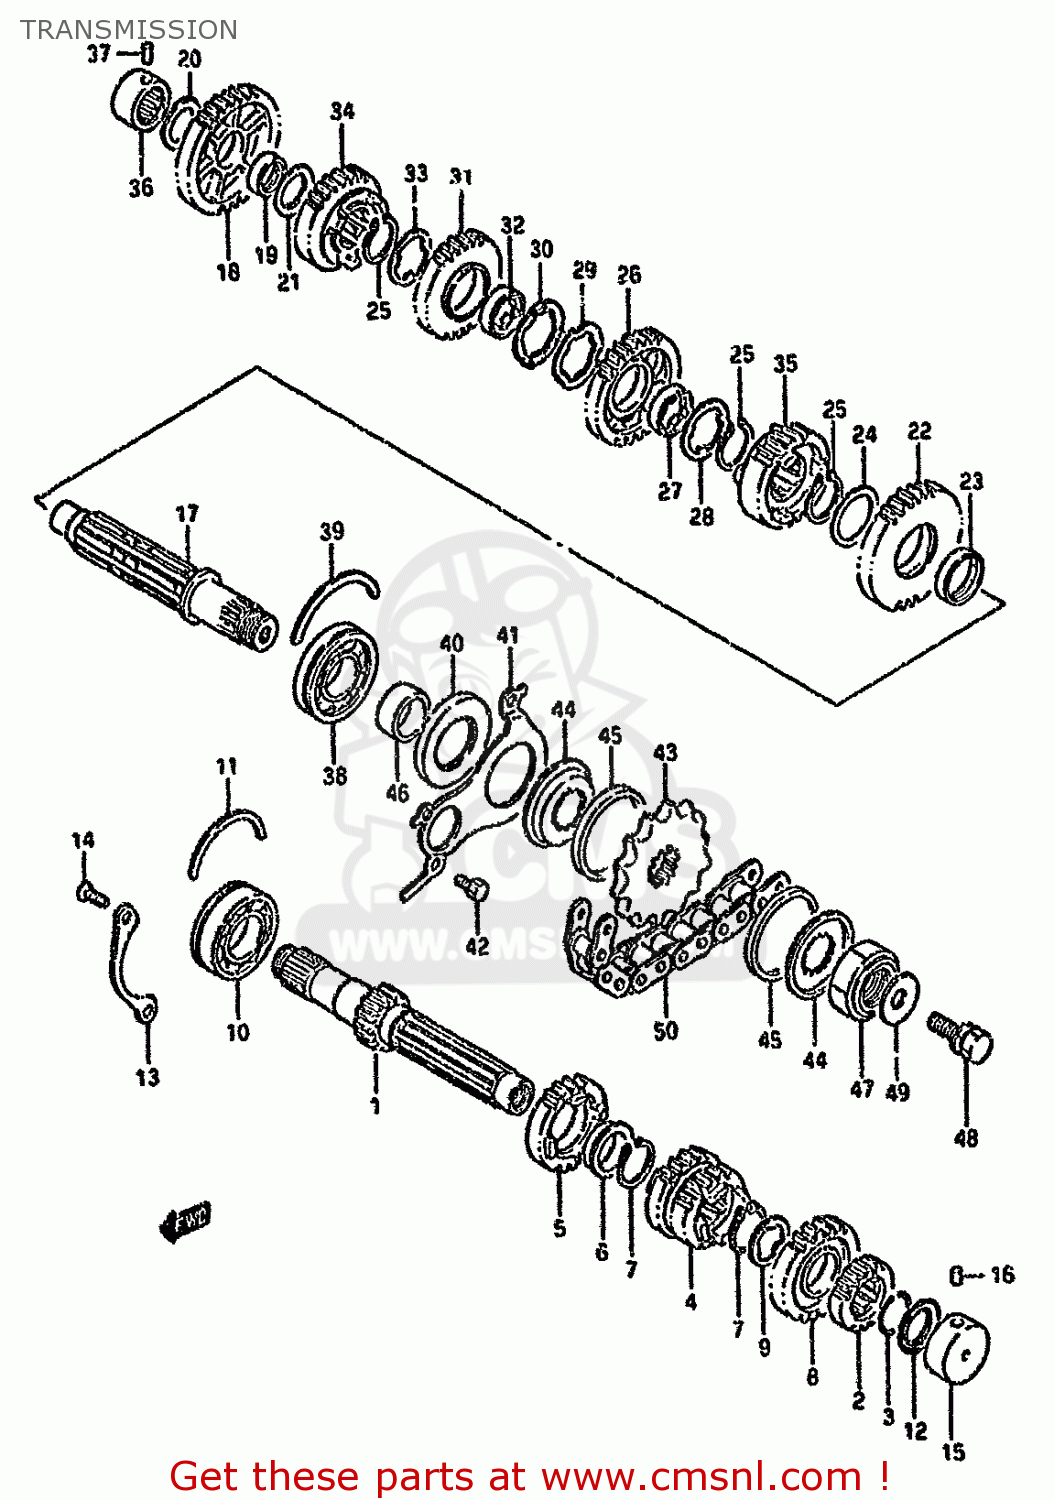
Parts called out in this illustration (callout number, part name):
1	SHAFT,COUNTER(NT:12)
2	GEAR,2ND DRIVE(NT:16)
3	CIRCLIP
4	GEAR,3RD & 4TH DRIVE(NT:17/20)
5	GEAR,5TH DRIVE(NT:22)
6	BUSHING
7	RING,SNAP
8	GEAR,SIXTH DRIVE
9	WASHER,LOCK
10	BEARING(25X62X17)
11	C-RING
12	SEAL,OIL(20X31.2X2.7)
13	RETAINER,CNTR SHAFT BEARING
14	SCREW
15	BEARING(20X34X17.5)
16	PIN
17	SHAFT,DRIVE
18	GEAR,FIRST DRIVEN
19	BUSH(22X26X9)
20	WASHER
21	WASHER
22	GEAR,2ND DRIVEN(NT:33)
23	BUSH(28X32X8)
24	WASHER, THRUST
25	CIRCLIP
26	GEAR,3RD DRIVEN(NT:28)
27	BUSH
28	WASHER,LOCK
29	WASHER,LOCK
30	WASHER
31	GEAR,4TH DRIVEN(NT:28)
32	BUSH
33	WASHER,LOCK
34	GEAR,5TH DRIVEN(NT:27)
35	GEAR,6TH DRIVEN
36	BEARING(20X34X20)
37	PIN
38	BEARING(25X62X17)
39	C-RING
40	SEAL,OIL(34X62X6)
41	RETAINER,DRIVE SHAFT OIL SEAL
42	BOLT
43	SPROCKET,ENGINE
44	HOLDER,SPROCKET DAMPER
45	DAMPER,SPROCKET
46	SPACER(25X34X16.1)
47	NUT
48	BOLT
49	WASHER
50	CHAIN,DRIVE(112LE)
